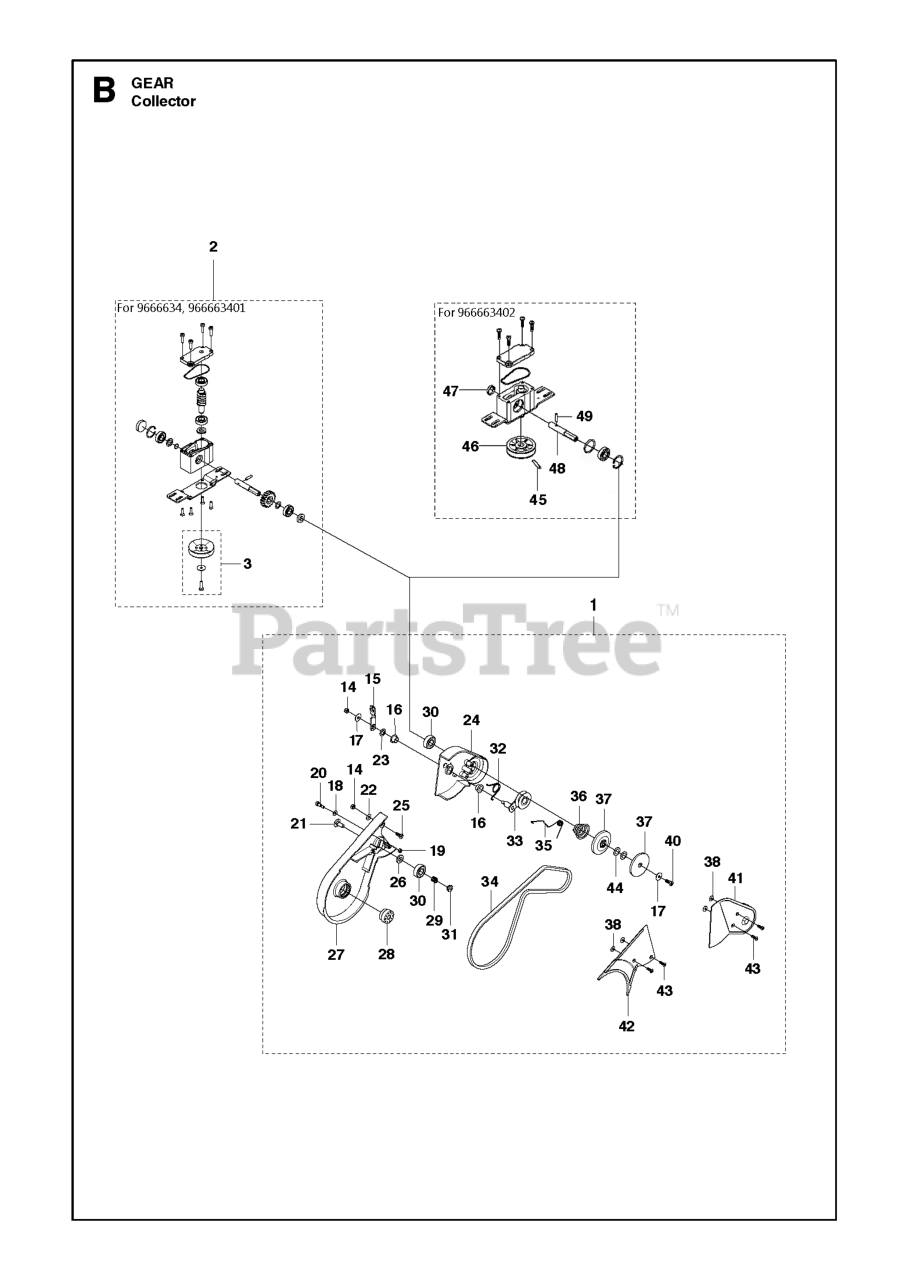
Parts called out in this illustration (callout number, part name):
14	NUT FLANGE - M6
17	WASHER 19X6X1
38	Washers
